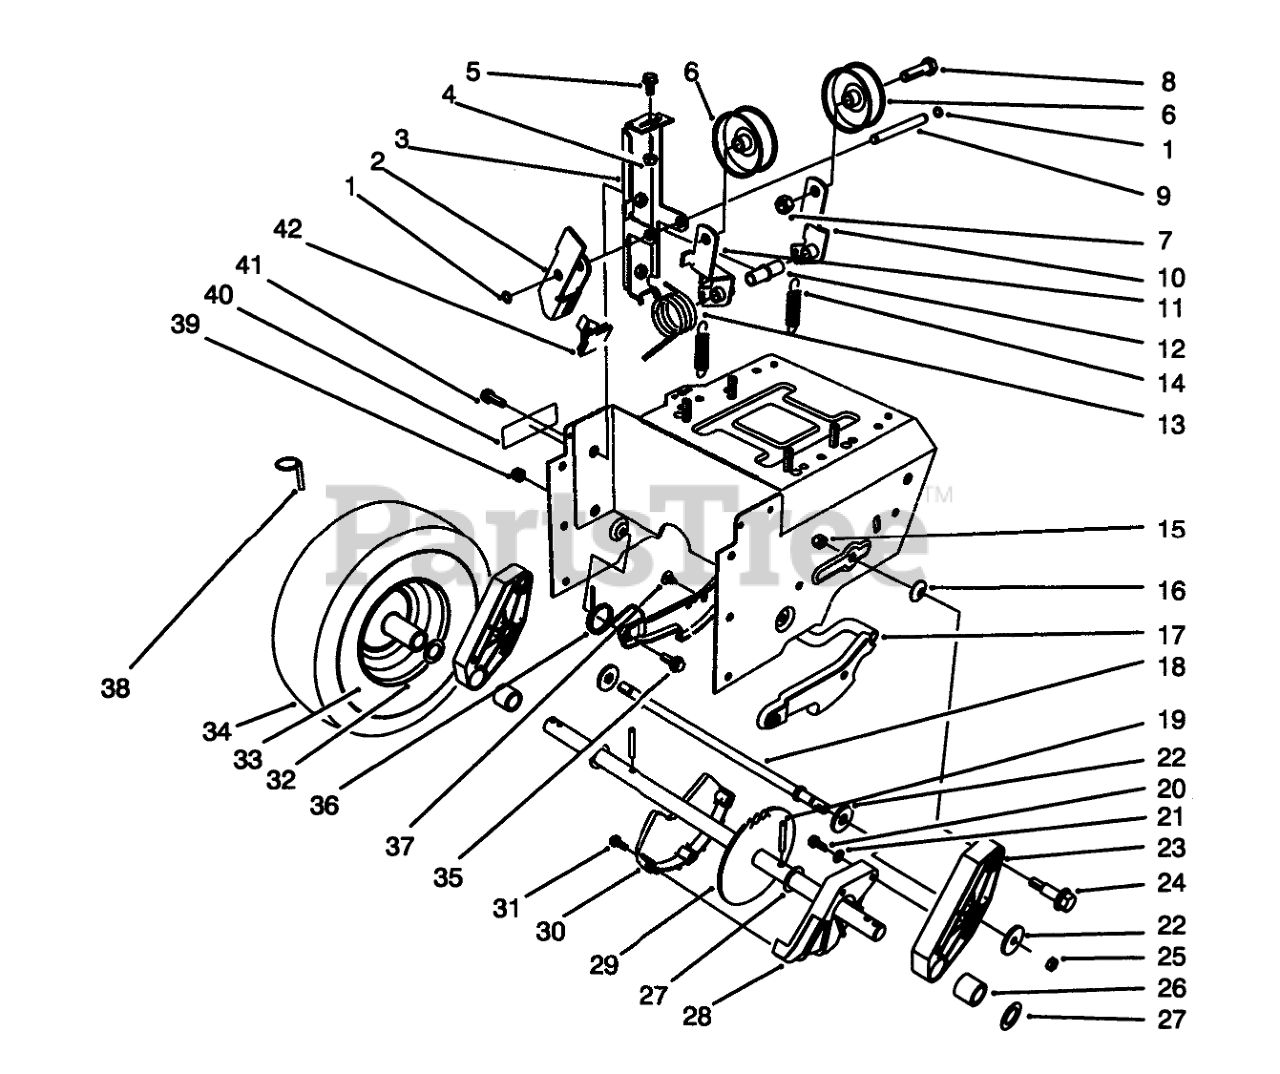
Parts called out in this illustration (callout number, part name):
1	RING-RETAINING
2	ARM-BRAKE
3	IDLER ARM BRACKET ASM
4	NUT-LOCK, NI
5	SCREW-HHF
6	PULLEY-IDLER
7	NUT-LOCK, NI
8	SCREW-HH
9	PIN-IDLER
10	ARM-IDLER, TRACTION
11	ARM-IDLER, IMPELLER
12	BUSHING-IDLER
13	TORSION SPRING
14	SPRING-EXTENSION
15	NUT-LOCK, NI
16	WASHER-SPRING
17	Latch-Arm
18	ROD-LATCH
19	PIN-ROLL, SLOTTED
20	SCREW-HWH
21	WASHER-FLAT
22	WASHER-SUPPORT
23	Pivot Arm Assembly (Incl. Ref. #26)
24	BOLT-SHOULDER
25	NUT-LOCK, NI
26	BUSHING-AXLE
27	WASHER-THRUST
28	GUARD-CHAIN, LH
30	GUARD-CHAIN, RH
31	Screw
32	RIM-WHEEL
33	INNER TUBE
35	SCREW-SHOULDER
36	SPRING-LATCH, TORSION
37	FASTENER-PANEL
38	PIN-LYNCH
39	NUT-LOCK, NI
40	DECAL-WARNING
41	SCREW-HHF
42	PAD-BRAKE
